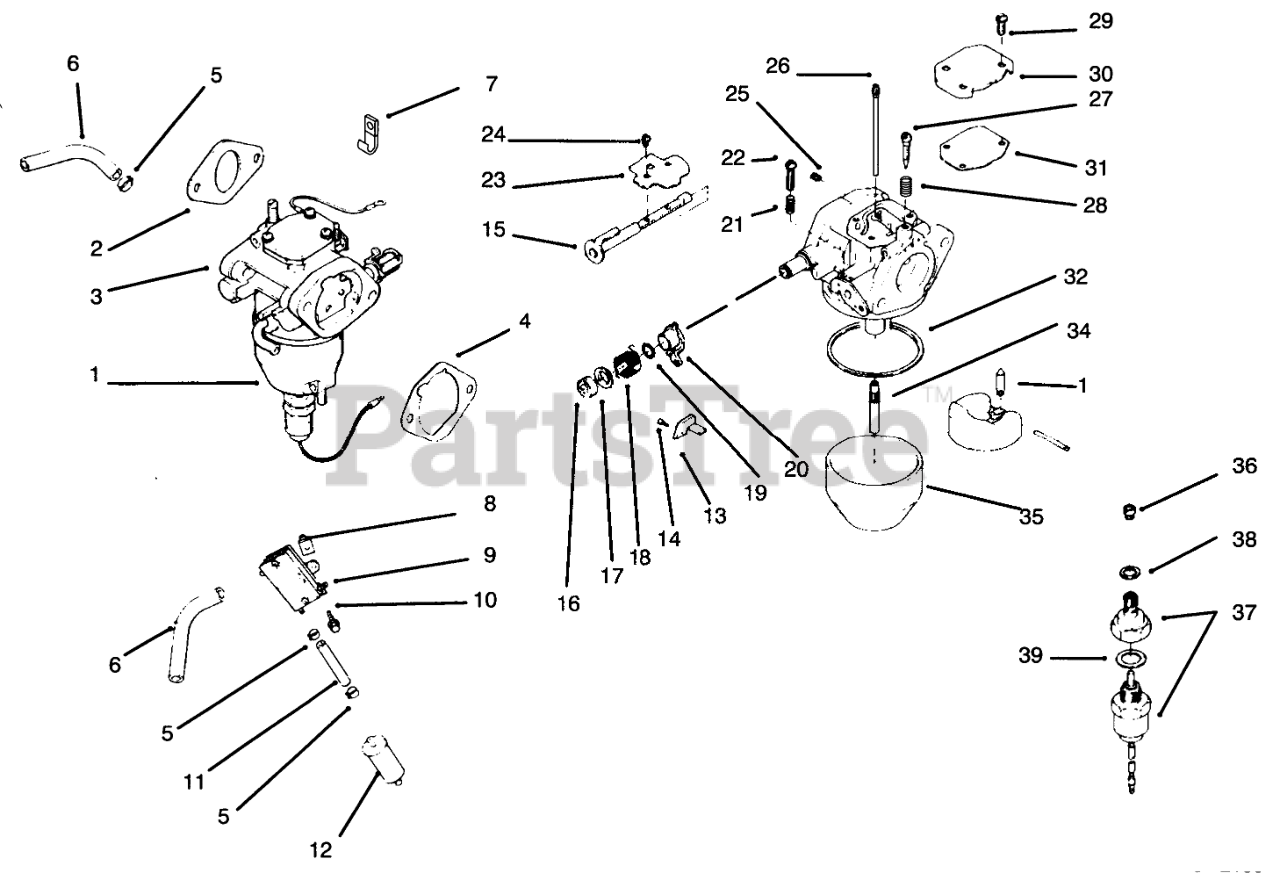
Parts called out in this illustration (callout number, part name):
1	Kit-Carburetor/Gasket (Incl. Ref. #2-4)
2	Gasket-Carburetor
3	Carburetor (Ref. Only)(Incl. Ref. #15-39)
4	Gasket-A/C Base
5	Clamp-Hose
6	Line-Fuel 12"
7	Clip-Cable
9	Pump-Fuel
11	Line-Fuel 10 1/2"
12	Filter-Fuel
13	Bracket-Throttle Stop
15	Shaft-Choke
16	Washer
17	Collar-Choke
18	Spring-Choke Return
19	Ring-Choke Lever
20	Lever-Choke
21	Spring-Throttle Screw
22	Screw-Throttle Adjust
23	Valve-Choke
24	Screw-Throttle Shaft
25	Jet-Air Bleed
26	Jet-Slow
27	Screw-Idle Adjust
28	Spring-Idle Adjust Screw
30	Cover-Passage
31	Gasket-Passage Cover
32	Gasket-Float Chamber
34	Nozzle-Main
35	Chamber-Float
36	Jet-Main
37	Kit-Solenoid Valve (Incl. Ref. #38-39)
38	Gasket-Chamber Screw
39	Gasket-Solenoid
